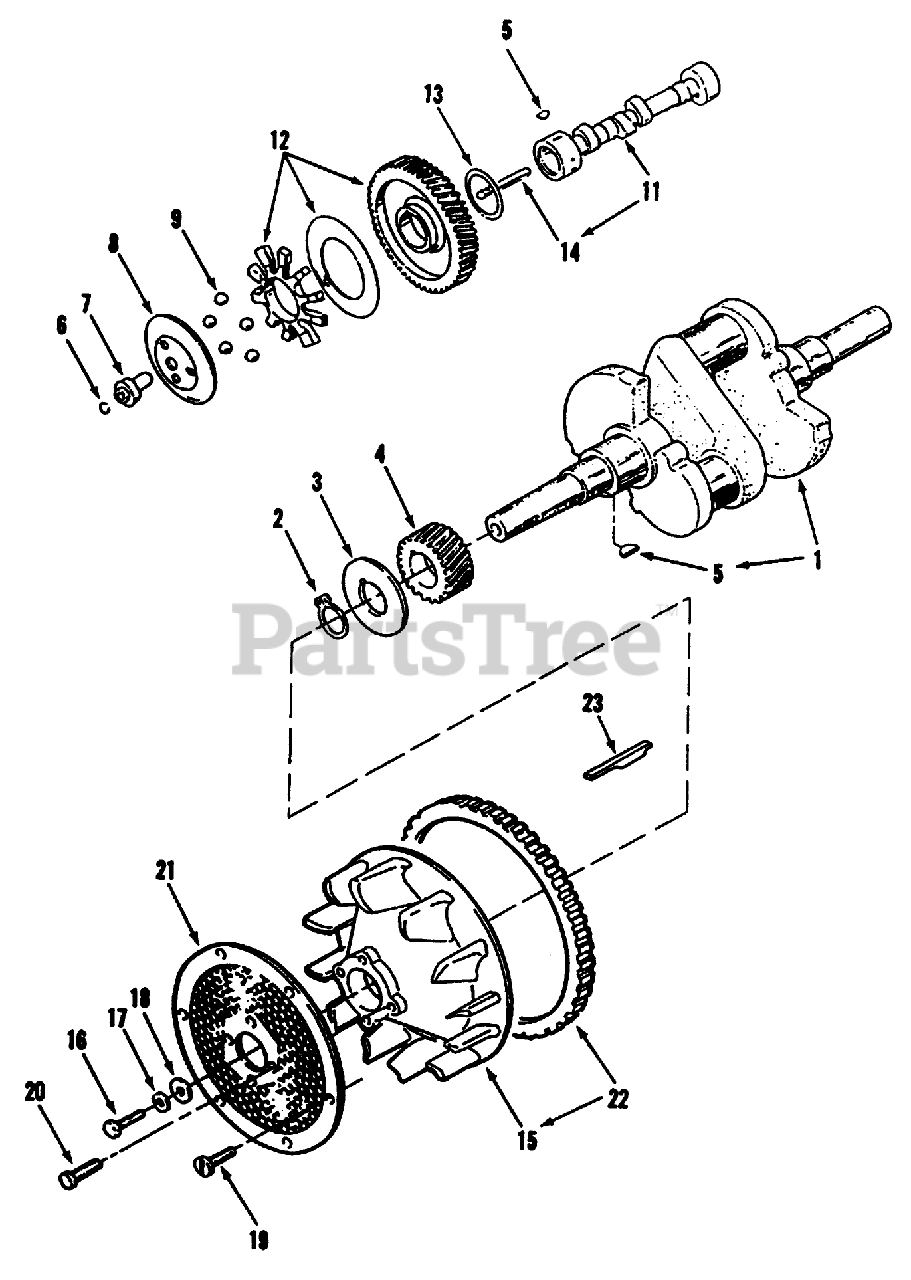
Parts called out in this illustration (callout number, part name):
1	Crankshaft
7	HUB-GOVERNOR CUP
8	CUP-GOVERNOR
9	BEARING
11	KEY-FLYWHEEL
13	WASHER-THRUST
14	PIN-CENTER
17	WASHER-FLAT
18	WASHER-FLAT
21	SCREEN-AIR INLET
23	KEY-FLYWHEEL
